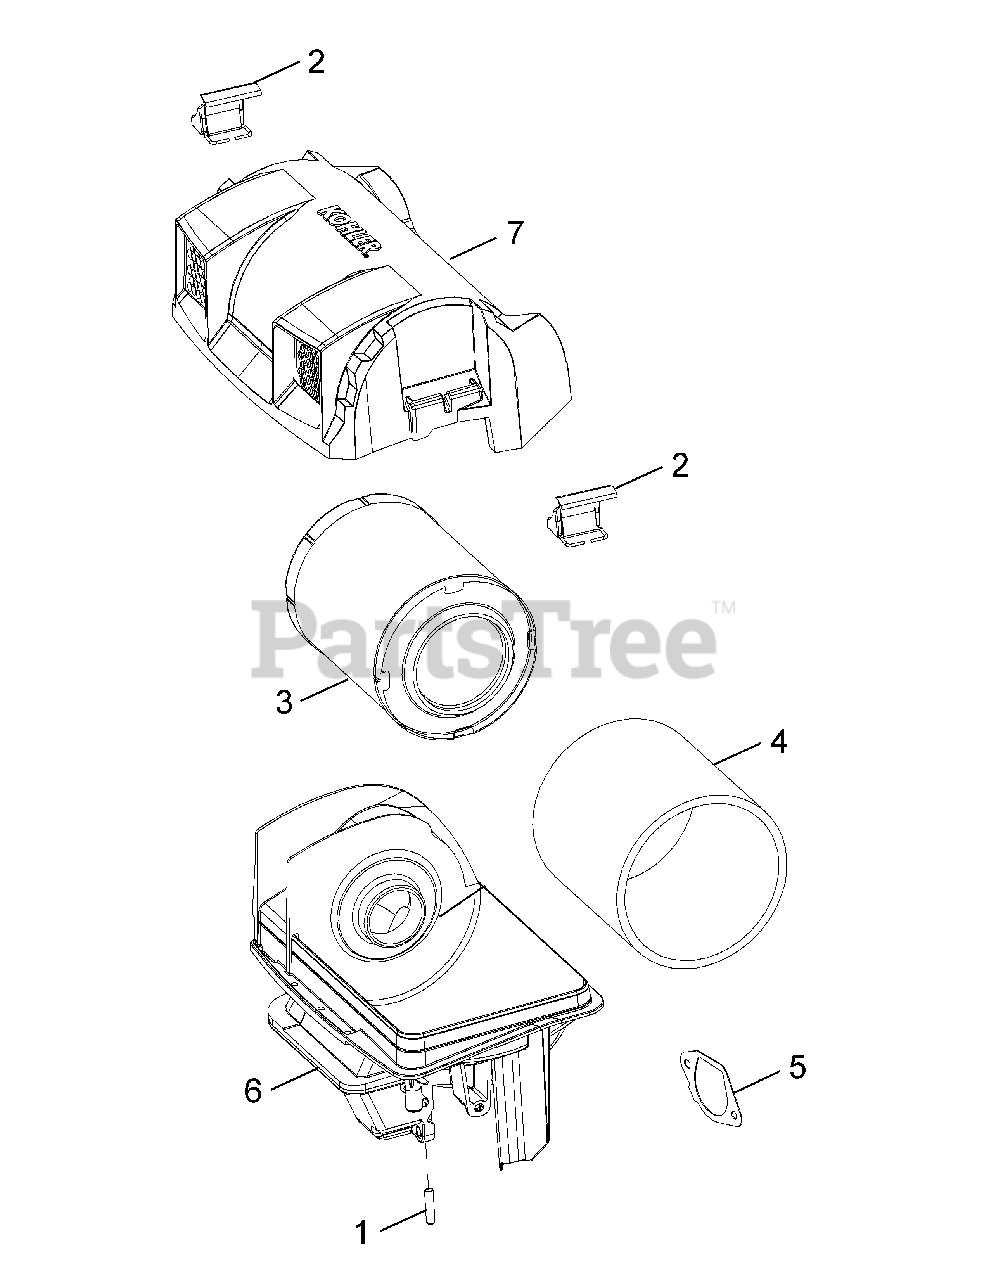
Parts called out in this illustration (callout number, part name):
2	Air Cleaner Cover Latch Assembly
3	Air Filter Element
4	Pre-Cleaner Element
5	Air Cleaner Base Gasket
6	Air Cleaner Base Assembly
7	Air Cleaner Cover
